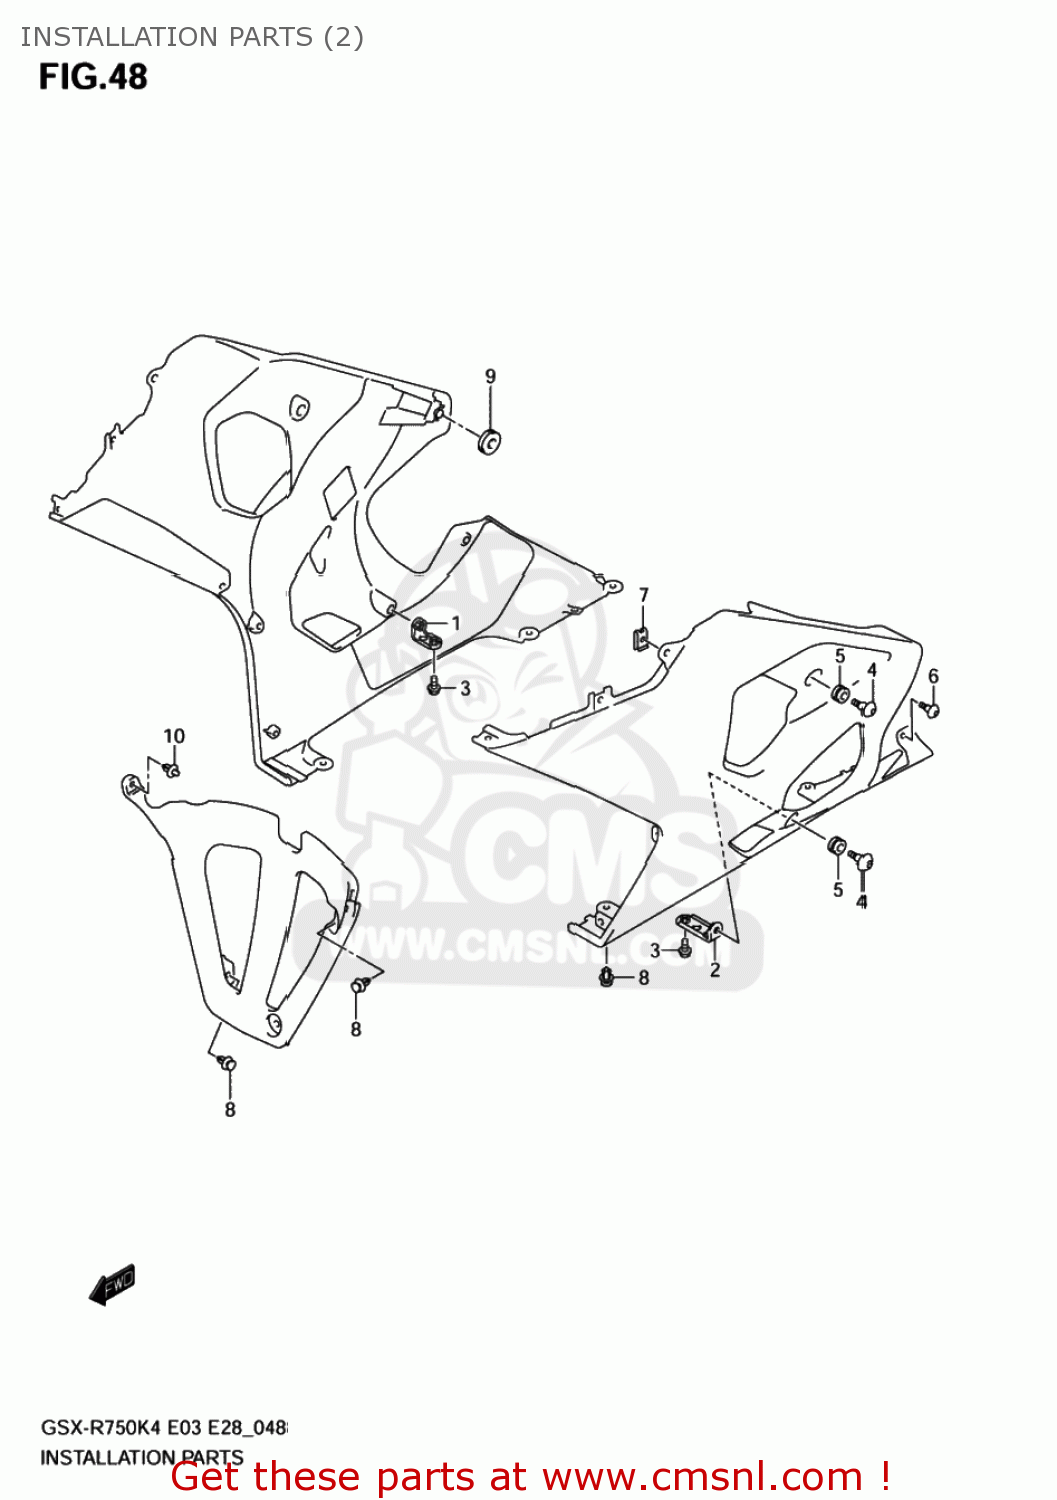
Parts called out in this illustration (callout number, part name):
1	BRACKET,UNDER COWLING LWR,R
2	BRACKET,UNDER COWLING LWR,L
3	BOLT
4	SCREW(6X20)
5	CUSHION
6	SCREW(5X13)
7	NUT,COWL
8	CLIP
9	CUSHION
10	CLIP(BLACK)
